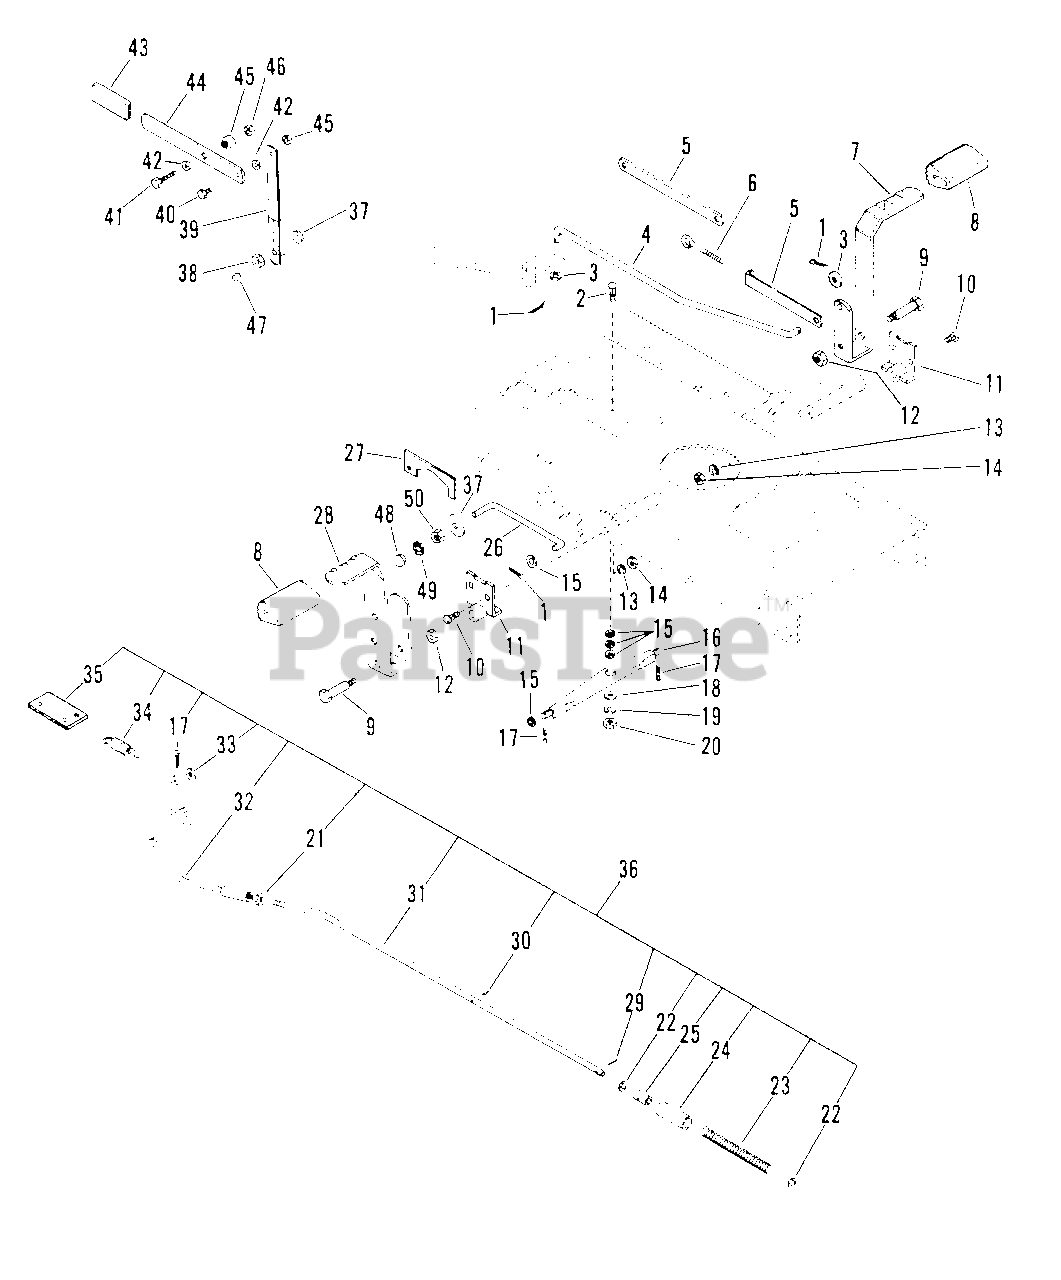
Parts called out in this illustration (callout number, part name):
1	PIN, COTTER .125X.75
2	BOLT, 3/8-16X1.25 RD HD SQ NK
3	WASHER, FLAT .438X1.000X.083
4	ROD, CLUTCH
5	LINK
6	EYEBOLT
7	PEDAL, CLUTCH
8	COVER, PEDAL
9	BOLT, SHOULDER
10	BOLT, CARRIAGE 5/16-18X.75
11	PIVOT, PEDAL
12	NUT, LOCK 3/8-16
13	WASHER, LOCK 5/16 SP
14	NUT, HEX 5/16-18
15	WASHER, .626 I.D.X3.85 O.D.
16	ARM, PIVOT
17	HAIRPIN, INTERNAL 3/32
18	WASHER, FLAT .406X.812X.065
19	WASHER, LOCK 3/8 REG.
20	NUT, HEX 3/8-16
21	NUT, HEX 3/8-24
22	WASHER, FLAT .406X.812X.065
23	SPRING
24	SLEEVE
25	SLEEVE
26	ROD, PARKING BRAKE
27	CAM
28	PEDAL, BRAKE
28	PEDAL, BRAKE NEUTRALIZER
29	PIN, SPRING
30	PIN, SPRING .125X.50
31	ROD, BRAKE
32	ROD, BRAKE
33	WASHER, FLAT .312X.734X.065
34	SPRING, EXTENSION
35	PLATE, ANCHOR
36	ASSEMBLY, BRAKE LINKAGE
38	NUT, LOCK 3/8-16
39	LINK
40	BOLT, HEX 1/4-20X.625
41	BOLT, HEX 1/4-20X1.50
42	WASHER, FLAT .281X.625X.065
43	GRIP
44	ARM
45	SPACER
46	NUT, LOCK 1/4-20
47	GRIP
48	KNOB, ADJUSTMENT CONTROL
49	WASHER, LOCK 3/8 EXT. TOOTH TYA
50	NUT, JAM 3/8-16 HEX
